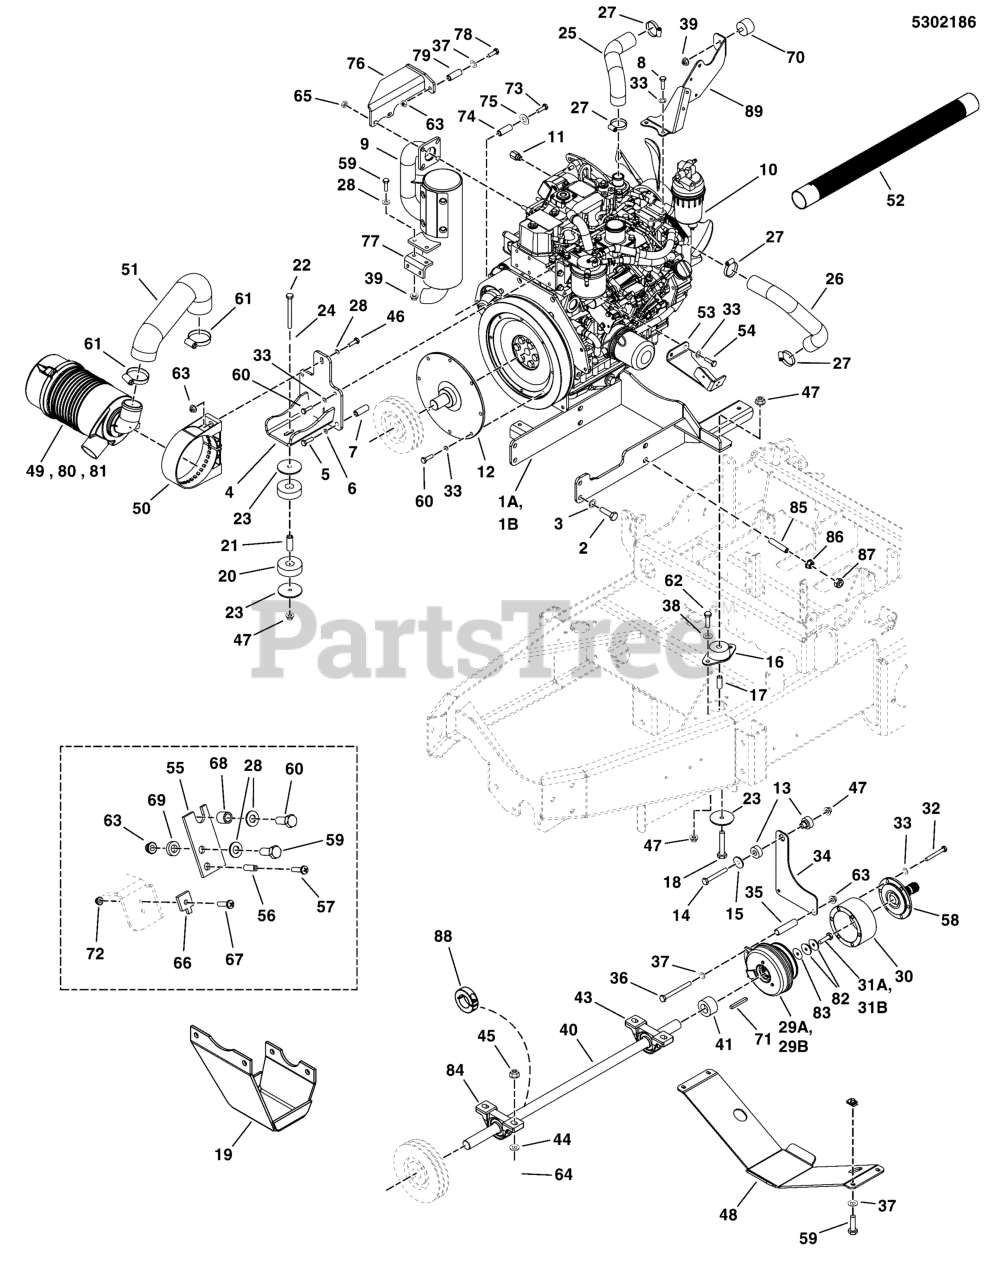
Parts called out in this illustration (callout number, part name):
2	CAPSCREW-HEX HD M12-1.75 X 25MM
3	WASHER, LOCK, 1/2 HI-ALLOY CZ
4	WELD, ENGINE MOUNT, REAR - RED
5	BOLT, M10-1.50 X 35
6	LOCKWSHER-SPRING M10 BLK (.403 ID)
7	SPACER, .41 X .88 X .20, YZ
8	BOLT, M8-1.25 X 25MM GD8.8
9	MUFFLER, YANMAR, S800X
10	ENGINE, YANMAR
11	SENDER, WATER TEMPERATURE
12	SHAFT, YANMAR 3TNV82A PTO
13	MOUNT, ISO, BOTTOM, RAD 5000Z-DIESEL
14	BOLT, 3/8-16 X 2, GD5, CZ
15	WASHER, .390 X 1.50 X .109, YZ
16	ISO MOUNT, FRONT, 155 LBS
17	SPACER, .38 X .50 X 1.33
18	BOLT, 3/8-16 X 2-1/4" GD5 CZ
19	PLATE, REAR PULLEY GUARD
20	ISO MOUNT, REAR, 490 LBS
21	SPACER, .38 X .62 X 1.62
22	BOLT, 3/8-16 X 3" GD5 CZ
23	WASHER, .39 X 2.50 X .125
24	WASHER, 3/8 GD.9 FLAT
25	HOSE, RADIATOR, UPPER, S800XY
26	HOSE, RADIATOR, LOWER, S800XY
27	CLAMP-HOSE WORM DR # 20 1.75-0.81 ST STL
28	WASHER, 5/16" SAE
30	SPACER, PTO DRIVE HUB, S800X YANMAR
32	BOLT, HEX M8-125 X 75, GD 8.8, YZ
33	WASHER, 5/16 LOCK CZ
34	PLATE, CLUTCH ANCHOR - RED
35	SPACER, .31 X .63 X 1.47, YZ
36	BOLT, 5/16-18 X 2-1/2 GD5 YZ
37	WASHER, 5/16 GD.9 FLAT
38	WASHER, 3/8 SAE
39	NUT, 5/16-18 HEX SERRATED FLANGE (LARGE)
40	SHAFT, PUMP DRIVE, S800X
41	SPACER, 1.00 X 1.88 X .57, CZ
43	BEARING, PILLOW BLOCK, 1
44	WASHER, 7/16 GD9 YZ
45	NUT, 7/16-20 HEX NYLON LOCK
46	BOLT, 5/16-18 X 1-1/4 GD5 YZ
47	NUT, 3/8-16 HEX NYLOCK FLANGE
48	PLATE, CLUTCH GUARD
49	AIR CLEANER ASSY
50	BRACKET, AIR CLEANER ASSY
51	HOSE, AIR CLEANER, S800XY
53	BRACKET, THROTTLE CABLE MOUNT - RED
54	BOLT, M8-1.25 X 16MM GD8.8
55	BRACKET, BARREL CLAMP SUPPORT
56	CLAMP, BARREL, THROTTLE
57	SCREW- #10-24 X 1/2 ROUND PHILLIPS
58	SHAFT, DECK DRIVE SPLINED
59	BOLT, 5/16-18 X 1 GD5 YZ
60	BOLT, M8-1.25 X 20MM GD8.8
61	CLAMP, SS HOSE 2-3/4
62	BOLT, 3/8-16 X 1" GD5 CZ
63	NUT, 5/16-18 HEX NYLOCK FLANGE
64	BOLT, 7/16-20 X 1-3/4" GD.5
65	NUT, HEX, M8-1.25, CZ, GD 8.8
66	CLAMP, CONDUIT
67	SCREW, #10-24 X 3/4 ROUND PHILLIPS
68	SPACER, .33 X .50 X .50, YZ
69	WASHER, .350 ID X .65 OD X .160 THK. YZ
70	MOUNT,ISO,TOP,RAD 5000Z-DIESEL
71	KEY, 1/4 SQ X 2-1/2
72	NUT, #10-24 HEX NYLON LOCK
73	CAPSCREW-HEX HD M08-1.25 X 50MM 8.8 BLK
74	SPACER, .33 X .50 X 1.50, YZ
75	WASHER, 5/16 FENDER
76	WELD, ALTERNATOR SUPPORT - RED
77	BRACKET, ADJ MUFFLER MNT
78	BOLT, 5/16-18 X 2, GD5
79	SPACER, .33 X .63 X 1.00, CZ
80	ELEMENT ASSY
81	AIR FILTER
82	BELLEVILLE WASHER 1.1875 X .442 X .089
83	SPACER, .45 X 1.88 X .38
84	BEARING, 1" GRIP-IT, PILLOW BLOCK
85	SOC SET SCREW, M12-1.75 X 70MM, SS CUP PT
86	HEX NUT, FLG, M12-1.75, SER, CZ NO SEALER
87	HEX NUT, NYLON INSERT
88	COLLAR, 1" SPLIT
89	WELD, FUEL PUMP MOUNT
